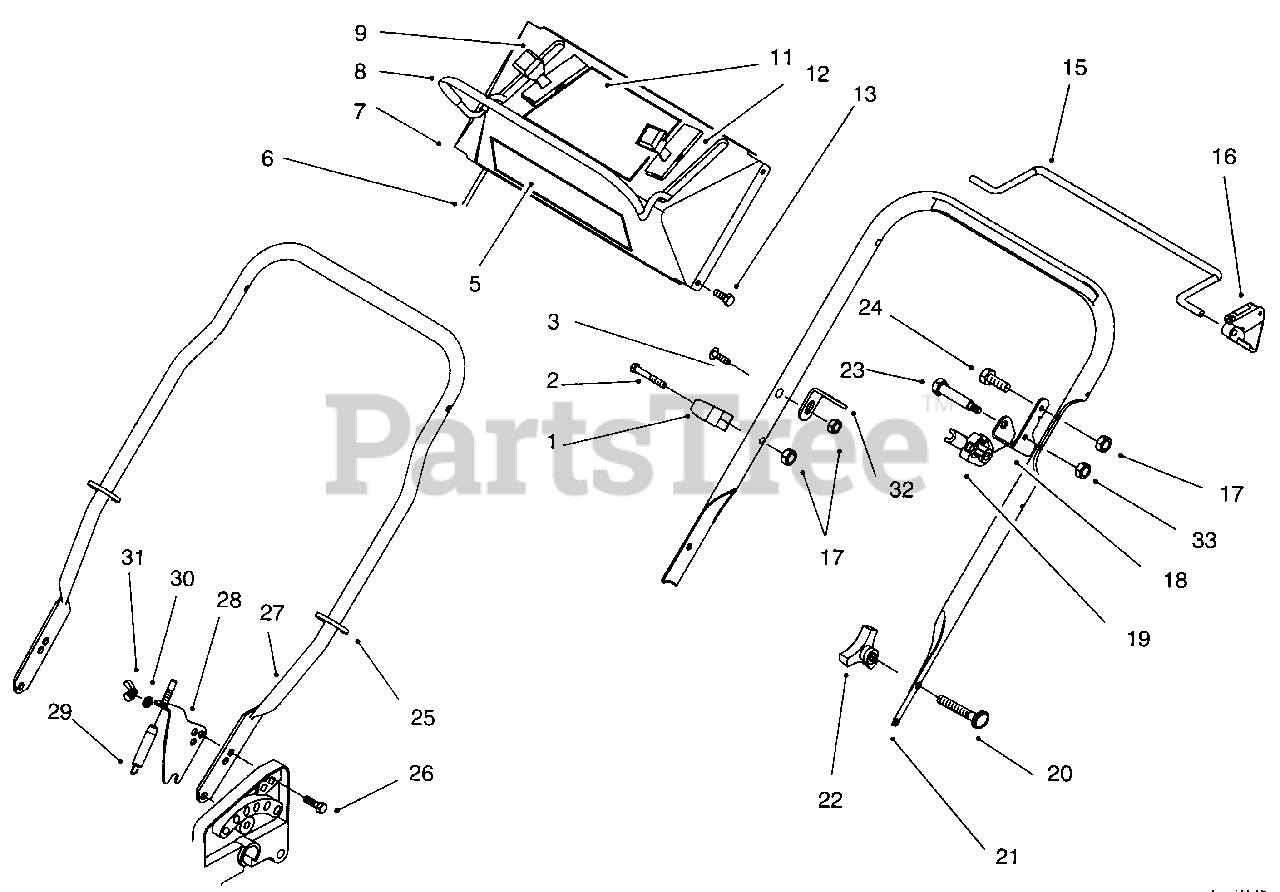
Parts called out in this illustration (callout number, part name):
1	Guide-Rope
5	Decal-Control Panel
6	Cable-Brake
7	Panel-Control (Incl. Ref. #11) (Model No.10418)
8	Bail-Brake
9	Control Ground (Model No.10517 & 10522)
11	Decal-Control Panel (Model No.10418)
12	Control-Throttle
13	Screw (Model No.10418 & 10517) (Model No.10522)
15	Bail-Control SP (Model No.10517 & 10522)
16	Stop-Pivot (Model No.10517 & 10522)
18	Bracket-Cam
19	Brake-BBC Cam
20	Screw-Handle
21	Handle-Upper
22	Knob-Handle
23	Bolt-Shoulder
24	Screw-Hex. Hd.
25	Tie-Cable
26	Bolt-Carriage
27	Handle-Lower
28	Bracket-Traction Cable (Model No.10517 & 10522)
29	Cable-Traction (Model No.10517 & 10522)
32	Bracket-Cable
33	Nut-Lock
